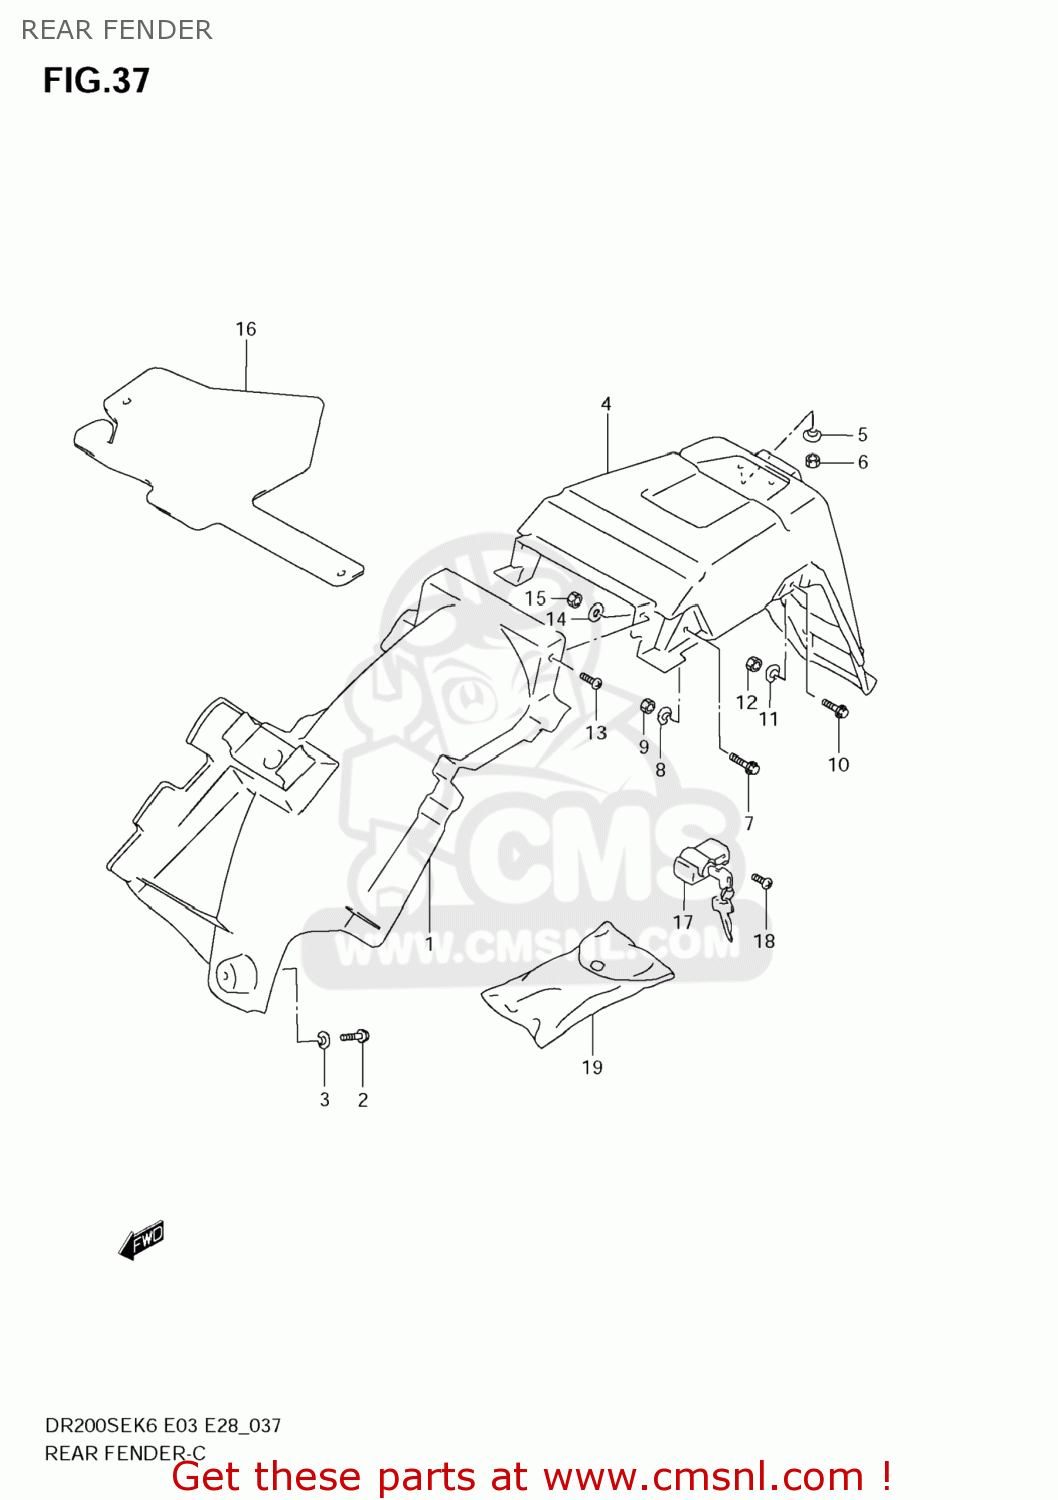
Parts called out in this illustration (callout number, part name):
1	BODY,RR FENDER FR
2	BOLT
3	WASHER
4	BODY ASSY,RR FENDER RR
5	WASHER
6	NUT
7	BOLT(8X25)
8	WASHER
9	NUT
10	BOLT
11	WASHER
12	NUT
13	SCREW
14	WASHER(6.5X18X1.6)
15	NUT
16	MUDFLAP,RR FENDER FR
17	LOCK SET,HELMET
18	SCREW(6X14)
19	TOOL ASSY
